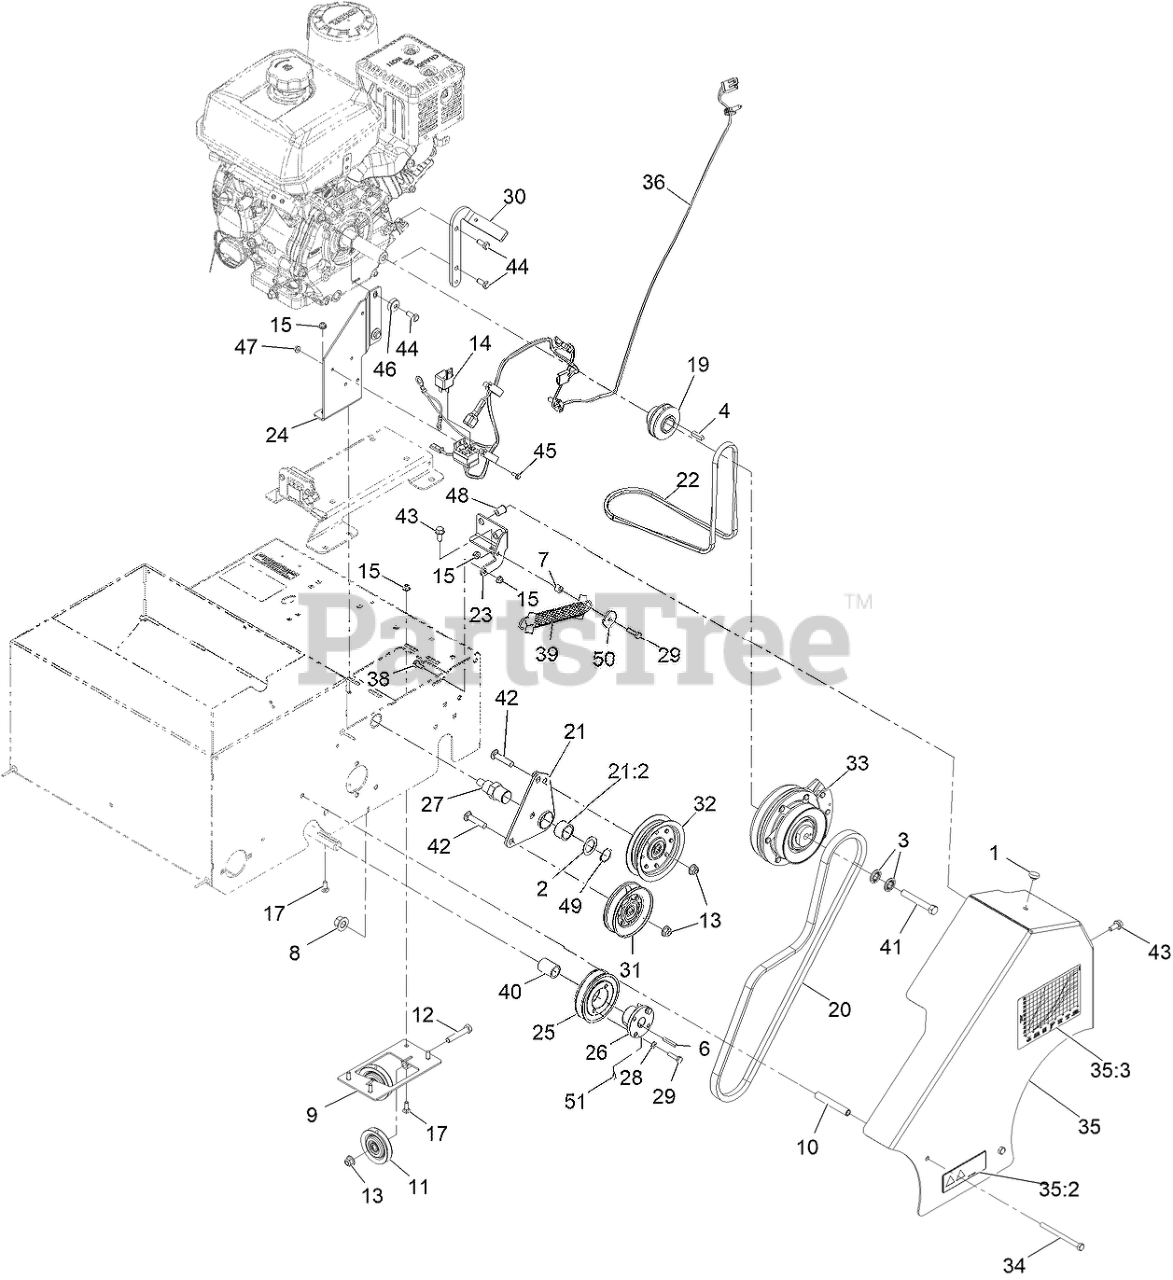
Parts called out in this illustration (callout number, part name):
2	WASHER-SPACER
3	WASHER-SPRING
6	KEY-SQUARE
8	Nut-Lock 1/2-13
9	PULLEY-TENSION
10	SPACER-KICKSTAND, LONG
11	PULLEY-IDLER
12	SCREW-HH
13	NUT-HF, NI
17	BOLT-CARR
19	PULLEY-MULE DRIVE
20	BELT-SEEDER, CLUTCH
21	IDLER ARM ASM
21:2	BUSHING
22	BELT-MULE DRIVE
23	BRACKET-SPRING
24	GUARD-BELT
25	SHEAVE-TAPER LOCK
26	BUSHING-TAPER LOCK
27	PIVOT-IDLER
28	WASHER-LOCK
29	SCREW-HH
30	STOP-CLUTCH
31	PULLEY-IDLER V
32	PULLEY-IDLER FLAT (4.06-I
33	CLUTCH-ELECTRIC
34	SCREW-HH
35	GUARD-BELT, W/DECALS
35:2	DECAL-DANGER
35:3	DECAL-GRAPH, SEED
36	HARNESS-WIRE
38	SCREW-HH
39	SPRING-EXTENSION
41	SCREW-HH
42	SCREW-CARR
43	SCREW-HHF
44	SCREW-HH
45	SCREW-HWH
46	WASHER-BELLEVILLE
47	NUT-LOCK, FLANGE
48	NUT-CLINCH
49	RING-RETAINING
50	WASHER
51	SCREW-SET, HS
